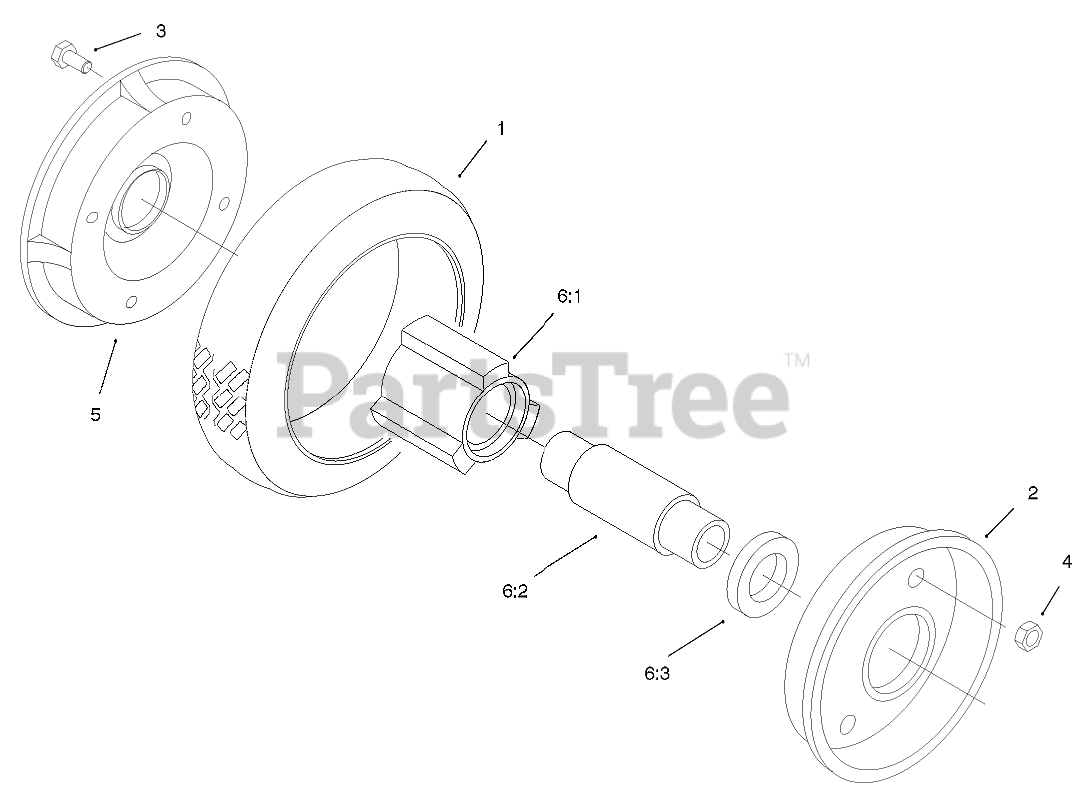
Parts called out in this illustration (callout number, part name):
2	PLATE-WHEEL, HALF
3	SCREW-HH
4	NUT-LOCK, NI
5	WHEEL HALF AND GEAR ASM
6	Hub and Bearing ASM
6:1	HUB-BEARING
6:2	SPACER-BEARING
6:3	BEARING-WHEEL
